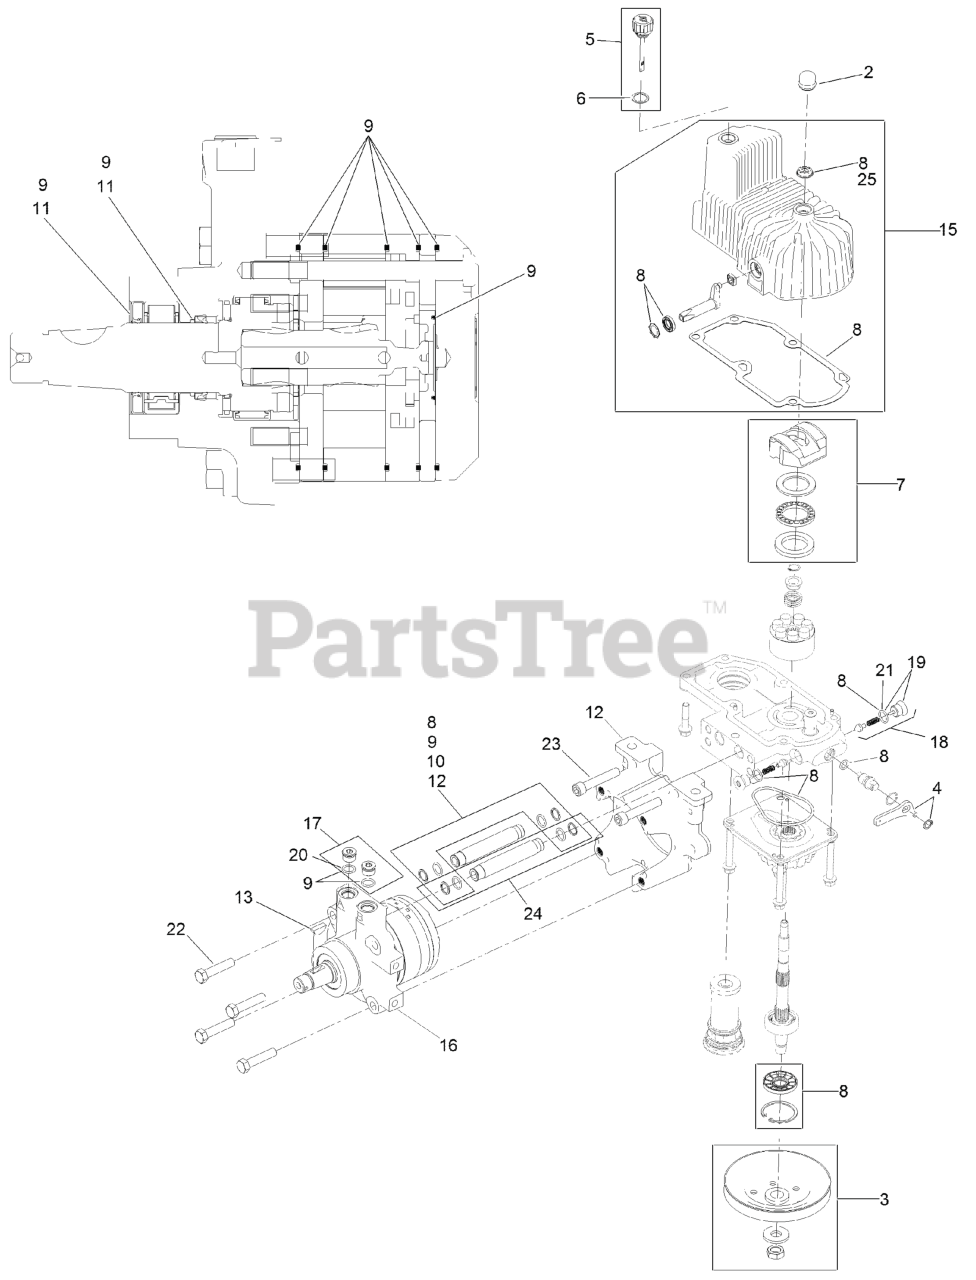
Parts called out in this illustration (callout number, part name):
2	COVER-SHAFT, HYDRO
3	PULLEY KIT
4	HANDLE-BYPASS VALVE, HYDRO
5	DIPSTICK-HYDRO W/GASKET
6	GASKET-DIPSTICK, HYDRO
7	SWASH BLOCK KIT
8	PUMP SEAL KIT
9	MOTOR SEAL KIT
10	TUBE SEAL KIT
11	OUTPUT SHAFT SEAL KIT
12	NOSE CUP-UHT
13	KEY-WOODRUFF
15	HOUSING-HYDRO, LH
16	MOTOR-HYDRAULIC LH 240CC
17	MAGNETIC PLUGS SERVICE KIT
18	CHECK VALVE ASM
19	PLUG-CHECK (W/O-RING)
21	O-RING-CHECK VALVE
22	SCREW HH
23	SCREW-HSH
24	HYDRAULIC TUBE KIT
25	SEAL-FAN DRIVE
26	KIT, PUMP SECTION 12CC LH NO FAN
27	ROTATING KIT
